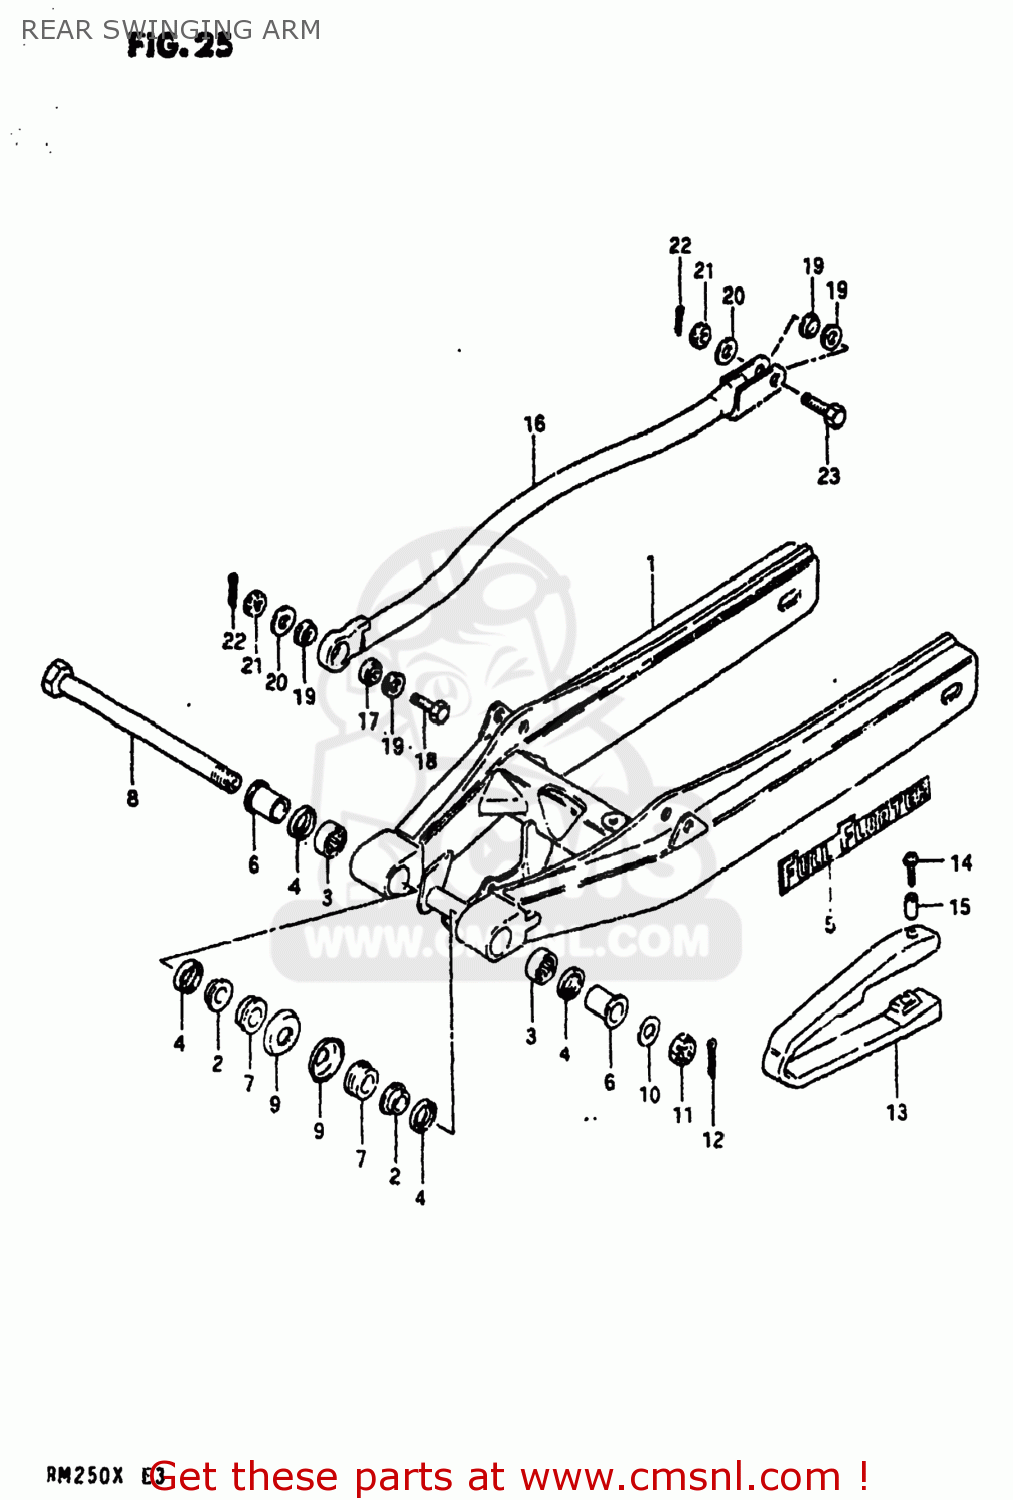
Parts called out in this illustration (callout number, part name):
1	SWING ARM ASSEMBLY,REAR
2	BUSH,RR SWINGINGARM PIVOT
3	BEARING(20X27X20)
4	OIL SEAL
5	EMBLEM,SWING ARM
6	SPACER,RR SWGARM PIVOT
7	SPACER,RR SWGARM PIVOT INNER
8	SHAFT,RR SWINGINGARM PIVOT
9	COVER,RR SWGARM DUST SEAL
10	WASHER
11	NUT 14MM
12	COTTER PIN
13	BUFFER,CHAIN TOUCH DEFLECTOR
14	SCREW,CHAIN TOUCH DEFEND
15	SPACER (5.5X8X4)
16	LINK,REAR TORQUE
17	SPHERICAL BRNG,TORQUE LINK
18	BOLT 8X28
19	20
20	WASHER
21	NUT 8MM
22	PIN 20X20
23	BOLT 8X29.5
